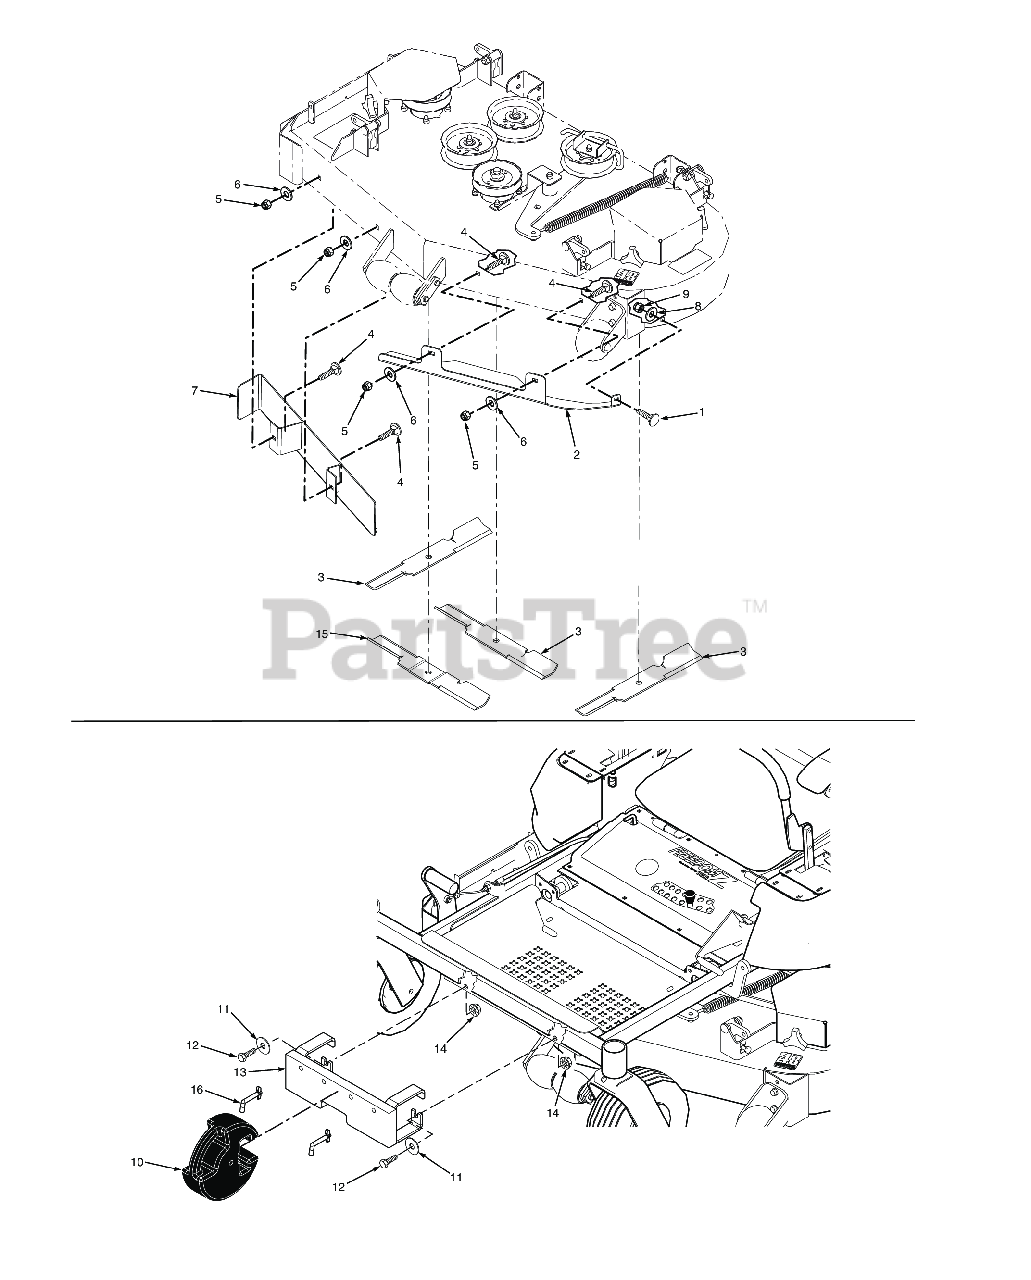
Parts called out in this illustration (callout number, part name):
1	Bolt, 5/16-18 x .75 RHSN Carriage
2	Baffle, LH - 48" Deck
2	Baffle, LH - 52" Deck
2	Baffle, LH - 61" Deck
3	Cutter Blade 18" Hi Lift (marbane)
3	Cutter Blade 16-1/2" Hi Lift (marbane)
3	Cutter Blade, High Lift (61" Deck)
4	Carriage Bolt, 3/8-16 x 1.0"
5	HEX NUT, ELASTIC STOP LOCK, 3/8-16
6	Flat Washer, 1/2 (.562 x 1.375 x .109)
7	Baffle Weldment,RH - 36" Deck
7	Baffle Weldment, RH - 48" Deck
7	Baffle, Weldment, RH - 52" Deck
7	Baffle, Weldment, RH - 61" Deck
8	Flatwasher, 5/16-.344 x .688 x .065 (48V / 52V)
9	Nut, Center Lock, 5/16-18(32)
10	Weight
11	Flat Washer, 1/2 (.562 x 1.375 x .109)
12	Bolt, Hex Head 1/2-13 x 1-1/4"
13	Support Weldment, Weight Mounting
14	Nut, Hex Serrated Flange 1/2-13
15	Cutter Blade, Cross - 36" & 52" Deck
15	Cutter Blade, Cross - 48" Deck
15	Cutter Blade, Cross - 61" Deck
16	Pin, Weight Retention
